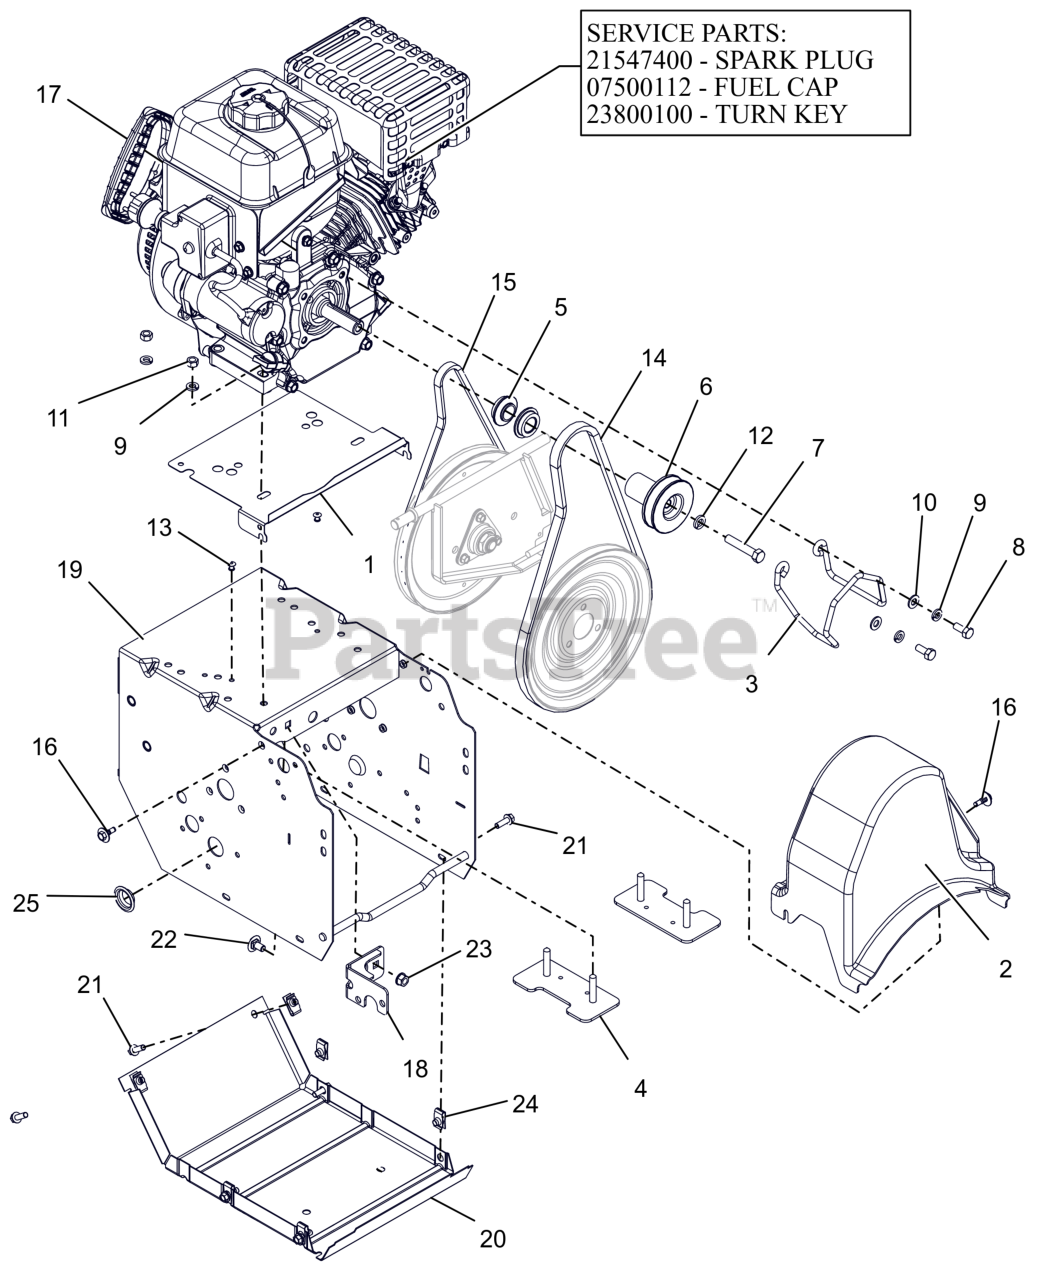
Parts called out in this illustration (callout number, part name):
1	BAFFLE, COMPACT
2	COVER, COMPACT BELT
3	FINGER, BELT
4	STRAP, ENGINE BOLT-WELDMENT
5	SHEAVE, TRACTION HALF (KEYLESS)
6	SHEAVE, AUGER 3/4 - PM
7	BLT, HEX .38-24X2.00 G5 ZCC
8	BLT, HEX .31-24X.750 G5 ZCC
9	WSHR, LK-HVY .312X.097 ZCC
10	WSHR,FLT .344X.688X.065 ZCC
11	NUT, HEX .312-18 ZCC
12	WSHR, LK-HVY .375X.115 ZCC
13	RVT, POP .1875 ZCC
14	V-BELT, HA-RAW EDGE
15	V-BELT, 3L-WRAPPED
16	SCR-TAP .25-20X.5 CAPTIVE
17	ENGINE, ARIENS AX208 240V
17	PLUG, SPARK
17	CAP, FUEL TANK BLACK
17	KEY, TURN LCT (2/PACKAGE)
18	WELDMENT, FRAME BRACKET
19	FRAME, MAIN
20	COVER, BOTTOM
21	BLT, HWH .25-20X.75 G5 ZCC
22	BLT, RHSSN .31-18X.625 G5 ZCC
23	NUT-LK-TOP-FLG .312-18 GF ZCC
24	NUT-RTNR .25-20X.56
25	PLUG, HOLE - 1.00" FLEXTEMP
